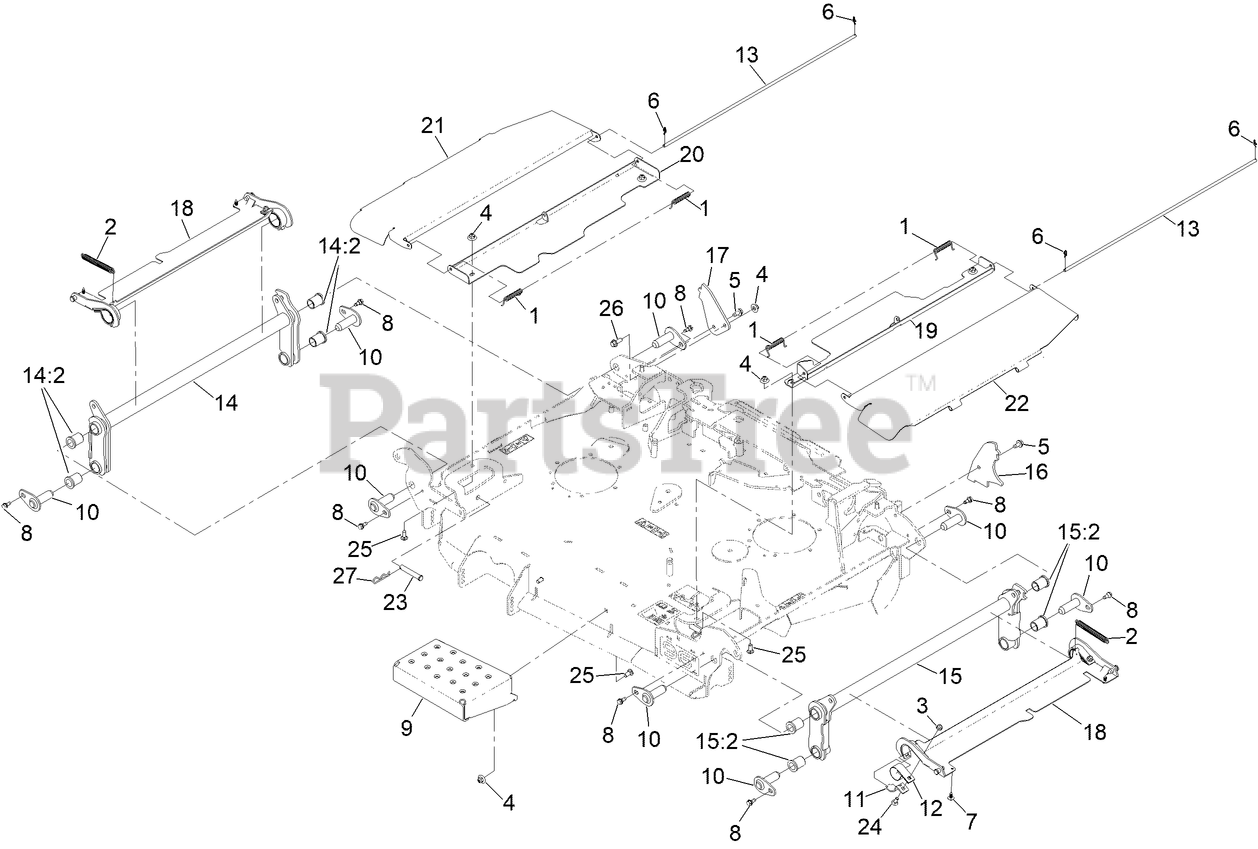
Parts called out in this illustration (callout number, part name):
1	SPRING-TORSION
2	SPRING
3	NUT-HF, NI
4	NUT-FLANGE, NI
5	SCREW-HWH
6	PIN-COTTER, LOCKING
7	PLUG-PLASTIC
8	SCREW-SHOULDER
9	PANEL-STEP
10	ASM-DECK PIN
11	PLATE-RETAINER, BEARING
12	BEARING-STRAP, NYLON
13	COVER-ROD, PIVOT
14	ASM-FOLS ARM, RH
14:2	BUSHING-FLANGED
15	ASM-FOLD ARM, LH
15:2	BUSHING-FLANGED
16	BRACKET-DECK STOP, LH
17	BRACKET-DECK STOP, RH
18	COVER-WING
19	SHIELD-CENTER, LH
20	SHIELD-CENTER, RH
21	PANEL-SHIELD HINGE, RH
22	PANEL-SHIELD HINGE, LH
23	PIN-CLEVIS
24	SCREW-CARR
25	BOLT-CARR
26	SCREW-HHF
27	PIN-HAIR
